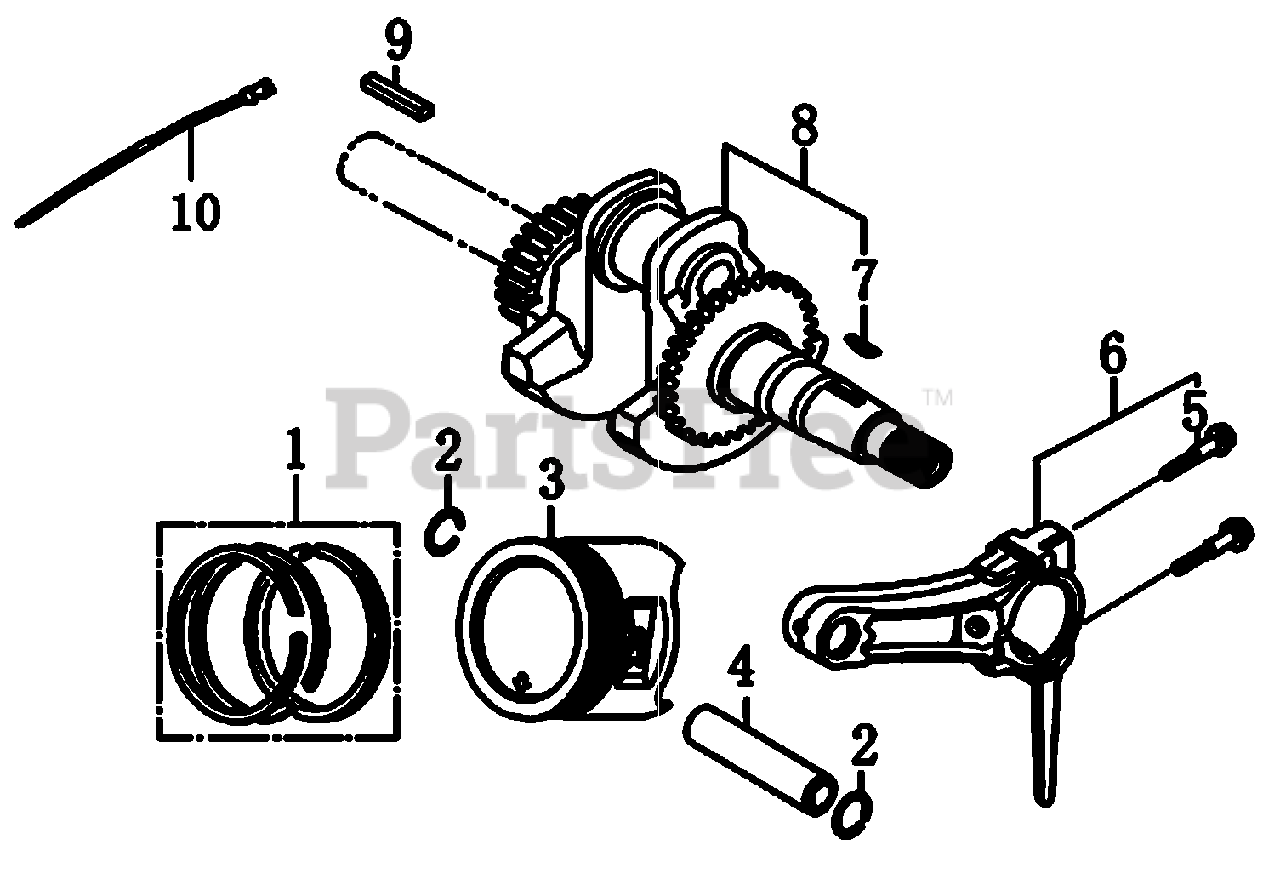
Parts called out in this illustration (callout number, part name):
2	CLIP, PISTON PIN
4	PIN, PISTON
5	BOLT, CONNECTING ROD
6	ROD ASSY, CONNECTING
8	CRANKSHAFT COMP
10	TIE WRAP UL 7.4"X .19" BLK
